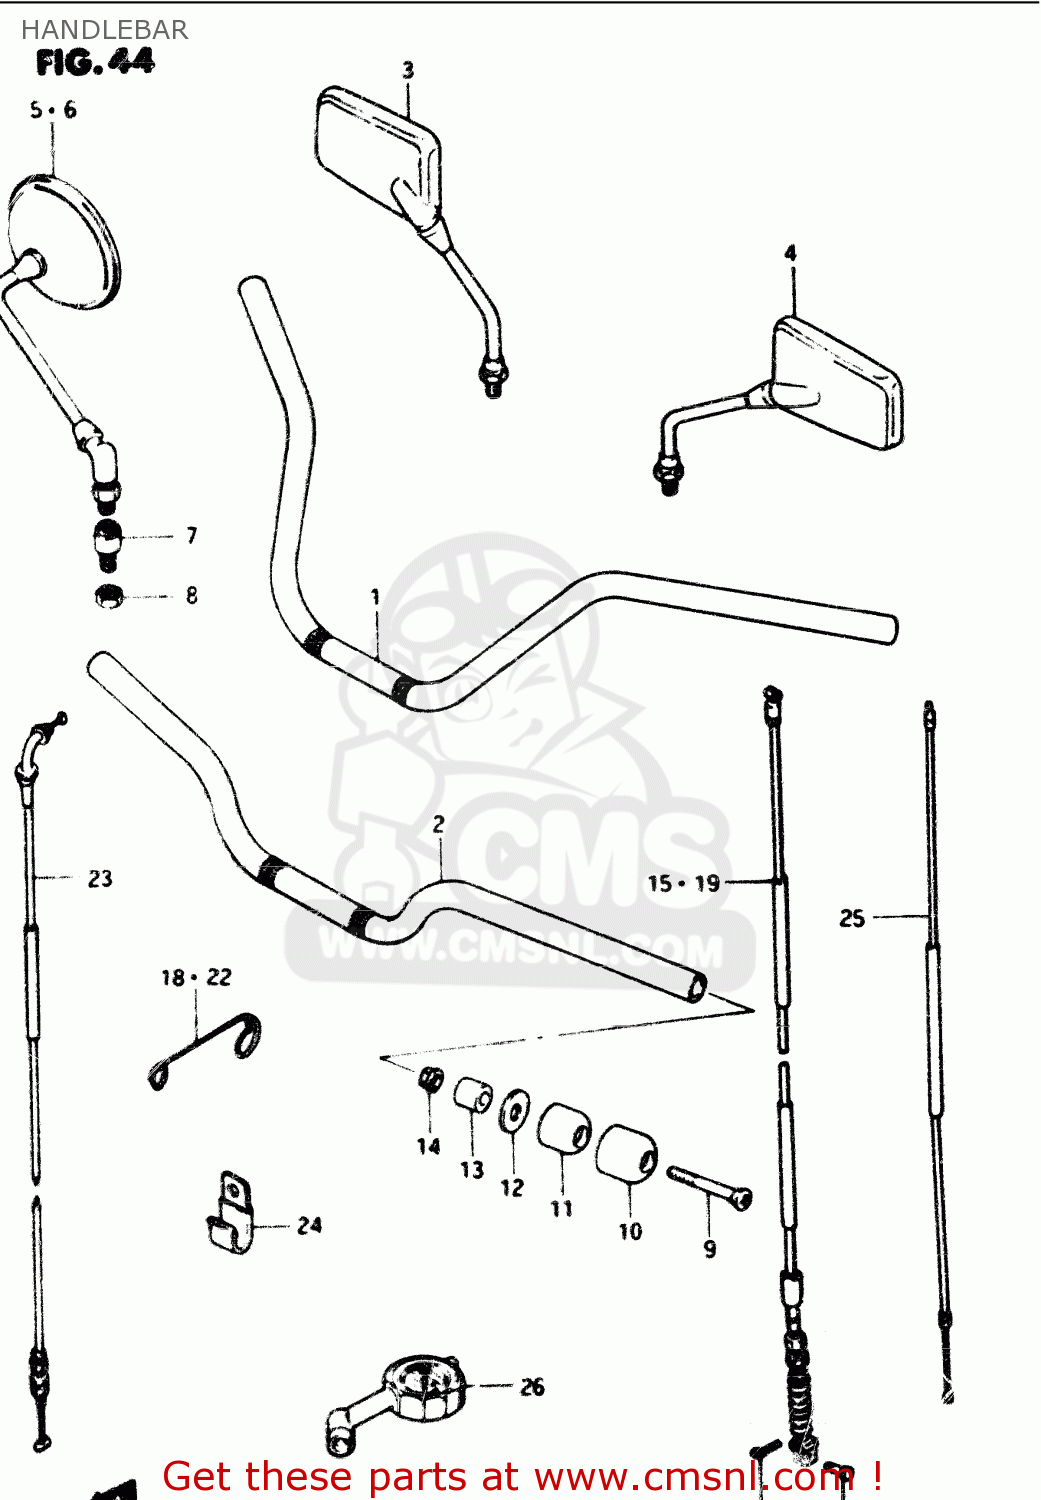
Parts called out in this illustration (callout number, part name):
1	HANDLEBAR
2	HANDLEBAR (FLAT)
3	MIRROR, REAR VIEW RH
4	MIRROR, REAR VIEW LH
5	MIRROR ASSY,RH
6	MIRROR, REAR VIEW LH
7	CUSHION,REAR VIEW MIRROR
8	NUT
9	SCREW
10	CAP,BALANCER
11	BALANCER,HANDLE
12	SPACER,BALANCER
13	EXPANDER,HANDLE BALANCER
14	NUT
15	CABLE ASSEMBLY,CLUTCH
16	PIN(L:15)
17	PIN
18	GUIDE,CLUTCH CABLE
19	CABLE ASSY,CLUTCH
20	PIN(L:15)
21	PIN
22	GUIDE,CLUTCH CABLE
23	CABLE ASSEMBLY,THROTTLE
24	CLAMP
25	CABLE, STARTER (FLAT)
26	GAUGE ASSY,AIR PRESSURE
